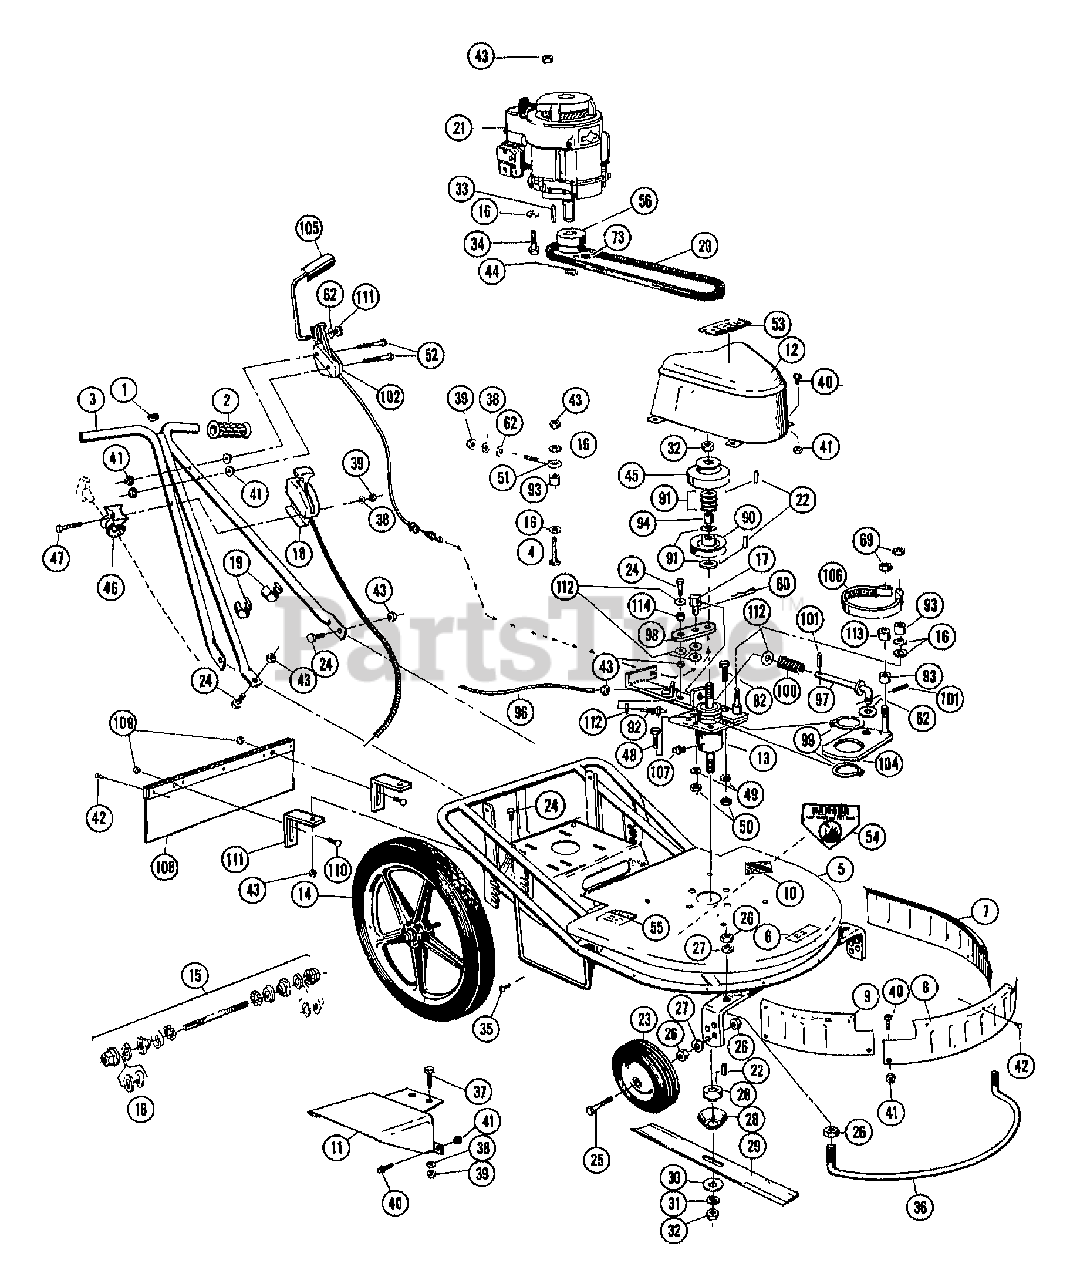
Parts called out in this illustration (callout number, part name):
1	PLUG-HANDLE
2	GRIP-HANDLE
3	ASSM-HANDLEBAR 22"
4	SCREW 5/16-18 x 2-1/4" HHC
6	CUTTING WIDTH DECAL 22
7	GUARD-LEFT 20" & 24"
8	GUARD-FRONT 22"
9	GUARD-RIGHT
10	DECAL-CAUTION
11	DEFLECTOR-DISCHARGE
12	HOOD-MOWER
13	ASSM-SPINDLE 22"
13	HOUSING-SPINDLE 22"
13	SHAFT-SPINDLE 22"
14	ASSM-WHEEL 16" W/KNOBBY
14	ASSM-WHEEL 16" W/O TIRE
14	TIRE-16" KNOBBY
15	DUST COVER SET (2)
16	WASHER-FLAT 5/16 SAE
17	PIN-CONNECTING ROD
18	CABLE-THROTTLE 22"
19	CLIP-THROTTLE CABLE
20	BELT-DRIVE #464-22"
21	ENGINE, BRIGGS 5HP, VERTICAL SHAFT #130902
21	ENGINE, BRIGGS 5HP, IC VERTICAL SHAFT #131922
22	KEY-3/16-1/2
23	WHEEL-FRONT 6"
24	SCR-HH 5/16-18X1.0 G5 ZP
25	SCR-HH 1/2X2.75
26	NUT-HEX JAM 1/2-13
27	WASHER-LK .5
28	KIT-BLADE ADAPTER
28	BLADE ADAPTER NUT
28	BEARING GUARD
29	BLADE-22" REPLACE PRO MWR
30	WASHER-FLAT 5/8
31	WASHER-LK .625 ZP
32	NUT-5/8 HEX
33	KEY-1/4 X L
34	SCR-HH 5/16-18X1.5 G5 ZP
35	SCR-#14 X .75
36	BUMPER-22"
37	SCR-HH 1/4-20 X .625
38	WASHER-LK .25 ZP
39	NUT-HEX 1/4-20 ZP
40	SCR-HH #10-24X.375
41	NUT-3/16 HEX LOCK
42	POP RIVET
43	NUT 5/16-18
44	RETAINER 1"
45	ASSM-DRUM/PULLEY
46	GUIDE-ROPE
47	SCR-HH 1/4-20 X 2.25
48	SCR-HH 3/8-16X1.0 G5 ZP
49	WASHER-LOCK 3/8
50	NUT-HEX 3/8-16 ZP
51	BOLT-EYE 1/4 X 3
52	SCR-HH #10-24 X 2.25
53	DECAL-"PRO"
54	DECAL-BLADE WARNING
55	DECAL-DISCHARGE CHUTE
56	CLUTCH-SINGLE 1 BORE
60	PIN-HITCH (24" MODEL)
62	WASHER-FLAT 1/4
69	NUT W/NYLON INSERT 3/8-24
73	SCR-SET 5/16 X .312
82	BOLT-HH 3/8-16X1.5 FTH ZP
90	PULLEY-3 1/2 X 5/8
91	WASHER-5/8 ID X .060
92	SWITCH-ENGINE STOP
93	BUSHING-ROCKER ARM
94	SPACER-5/8 ID X 1/2
96	GROUND WIRE ASSEMBLY
98	LEVER-BLADE BRAKE-84
99	RING-RETAINER
100	SPRING-BLADE BRAKE
101	PIN-ROLL 1/8 X .75
102	KIT-BBC CABLE
104	ASSM-BRKT BRAKE BAND
105	ASSM-HANDLE BLADE BRAKE
106	BAND-BRAKE 3 3/4
107	GREASE FITTING
108	ASSM-REAR GUARD
109	NUT-H/LK 5/16-18 NYLOCK
110	BOLT-CARRIAGE 5/16-18X1"
111	BRKT-MOUNTING 24"
112	WASHER - 5/16 SAE
113	SPACER-3/8 ID X 1/2
114	BUSHING-BRAKE LEVER-84
